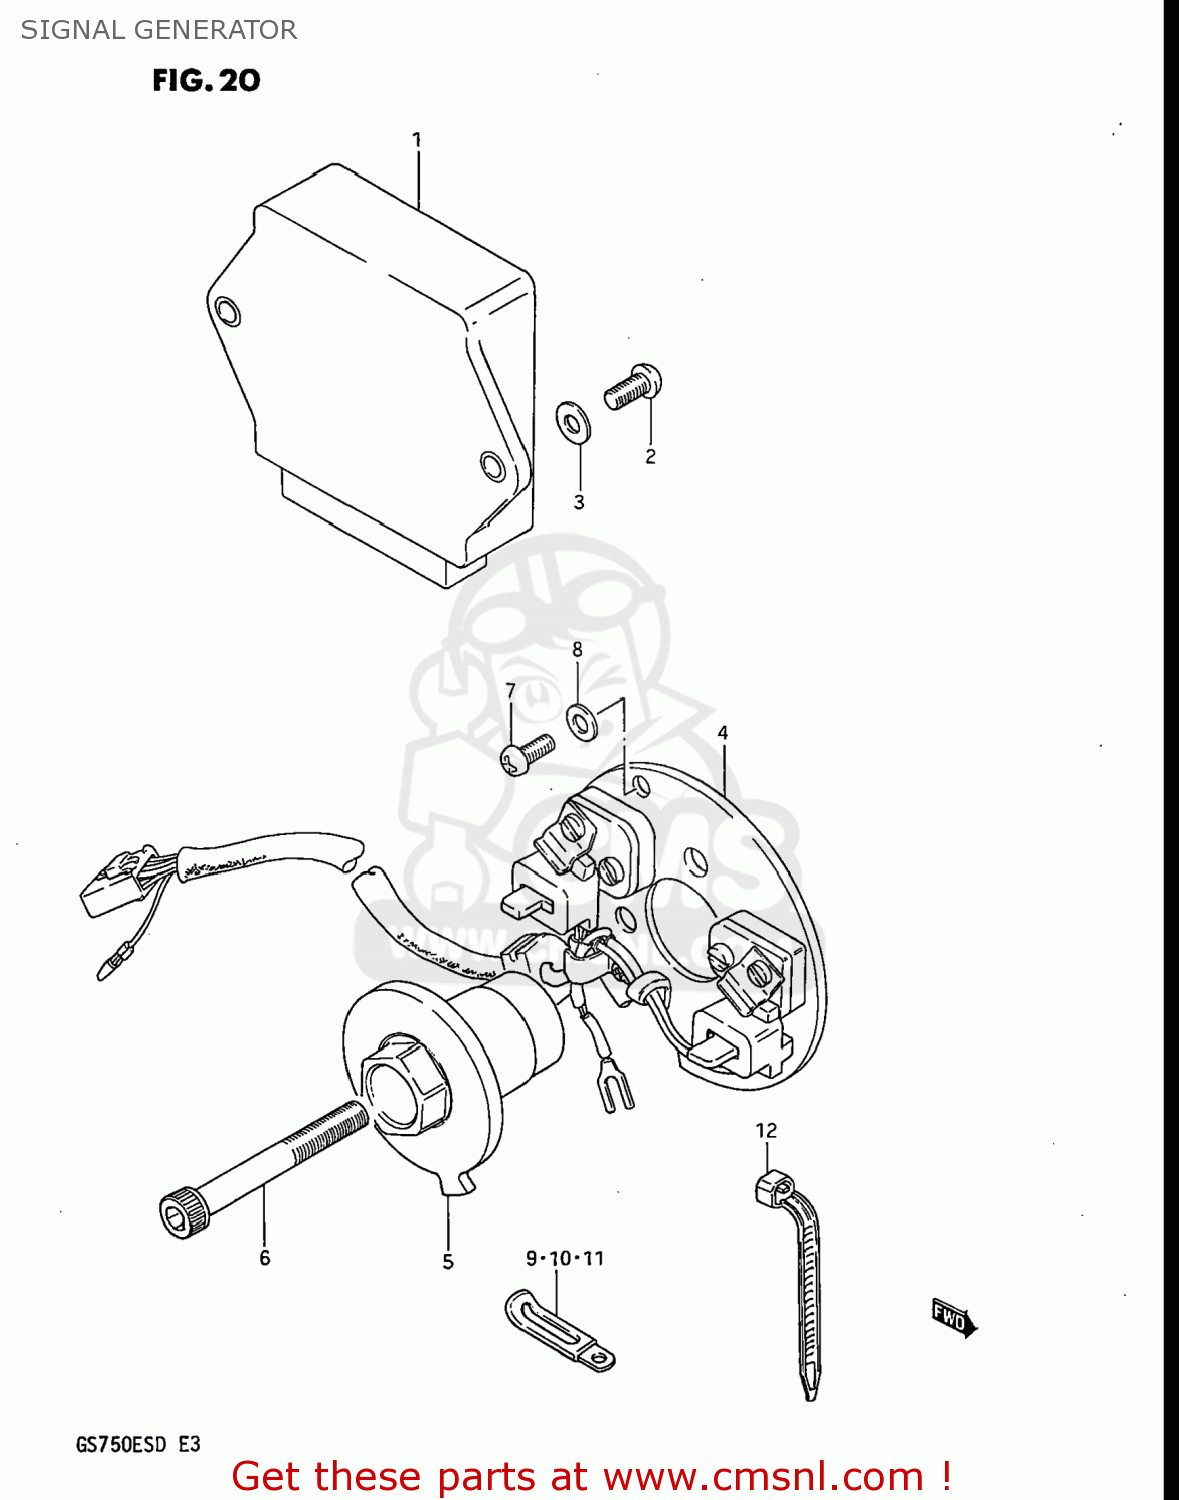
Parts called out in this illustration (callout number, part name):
1	IGNITER UNIT ASSEMBLY
2	SCREW 6X12
3	WASHER
4	STATOR,SIGNAL GENERATOR
5	ROTOR,SIGNAL
6	BOLT
7	SCREW(5X12)
8	WASHER
9	CLAMP L:35
10	CLAMP
11	CLAMP
12	CLAMP(L:125)
